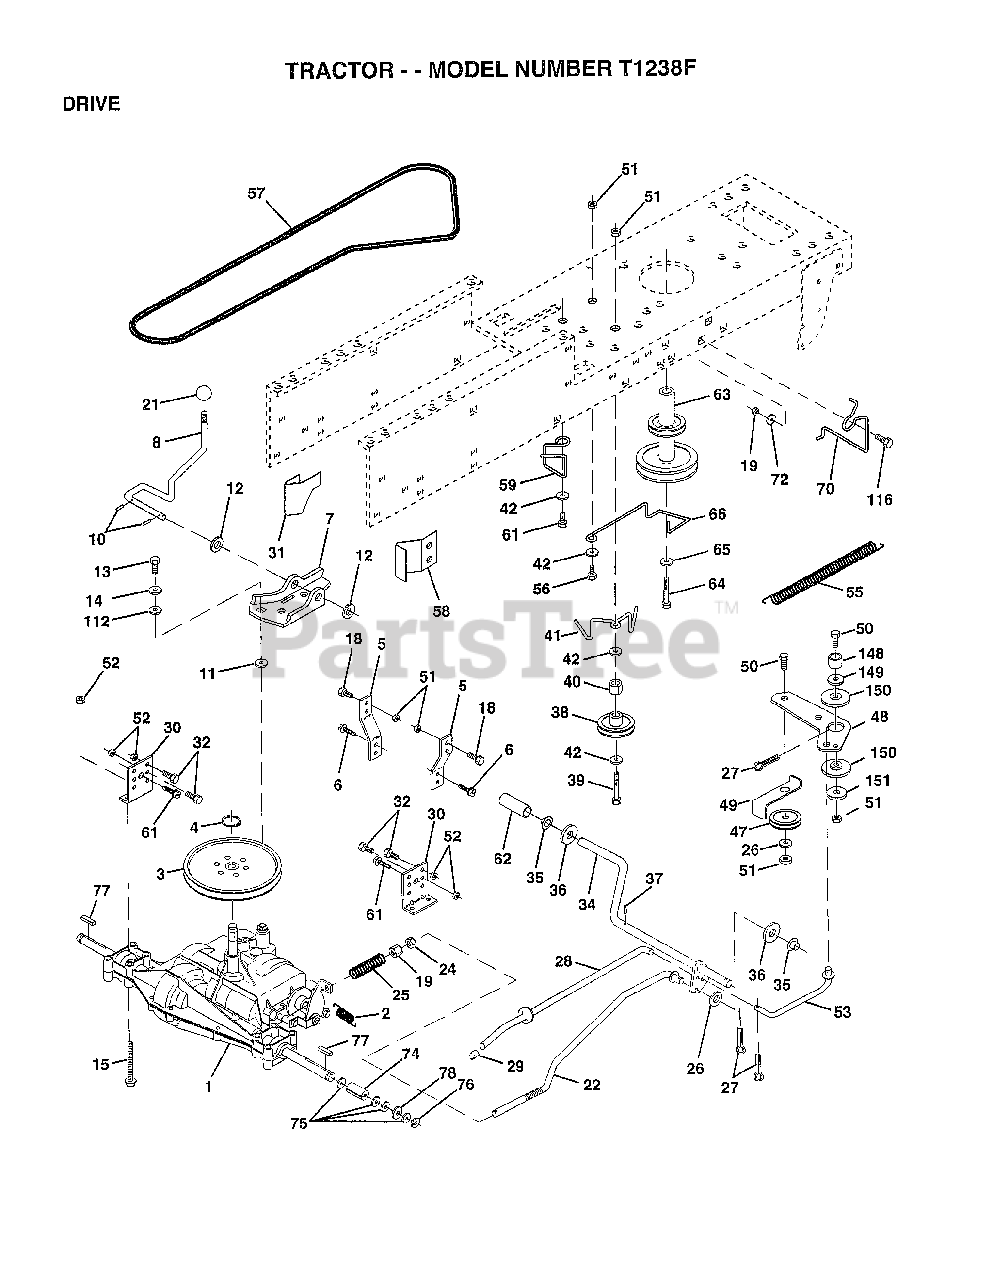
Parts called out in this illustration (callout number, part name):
2	SPRING.BRAKE.RETU
3	PULLEY TRANS
5	STRAP TORQUE
6	SCREW
7	BRKT.SADDLE.SHIFT
8	SHIFT ROD
10	PIN COTTER 1/8
11	WASH-SHFT PLT LT
12	WASHER
13	BOLT.1/4-28.W/PAT
14	LOCKWASHER
15	BOLT.HX.FLG.5/16
18	BOLT
19	NUT
21	KNOB T (1/2-HOLE)
22	BRAKE ROD
24	NUT
25	SPRING ROD LT
26	WASHER
27	COTTER PIN
28	ROD.BRAKE.PARK.LT
29	PLUNGER CAP T
30	TRANSAXLE MTG BKT
31	"KEEPER,BELT LH T"
32	BOLT
34	SHAFT ASM-PEDAL F
35	NYLON BEARING
36	WASHER LT
38	PULLEY.IDLER.FLAT
39	BOLT
40	SPACER T
42	WASHER
48	BELLCRANK.CLUTCH
49	RETAIN BELT
53	"LINK, CLUTCH T"
55	"SPRING, RETURN LT"
58	"KEEPER,BELT RH T"
59	KEEPER BELT CNTSP
61	SCREW
62	PEDAL COVER T
63	PULLEY.ENGINE
64	BOLT
65	LOCKWASHER
66	KEEPER-BELT
70	KEEPER BELT ENG
72	WASHER
74	SPACER LT
75	WASHER
76	E-RING LT
77	SQUARE KEY
78	WASHER
112	WASHER LT
116	BOLT RDHD 3/8-16
149	SPACER RETAINER
150	BUSHING.NYLON
151	WASHER
